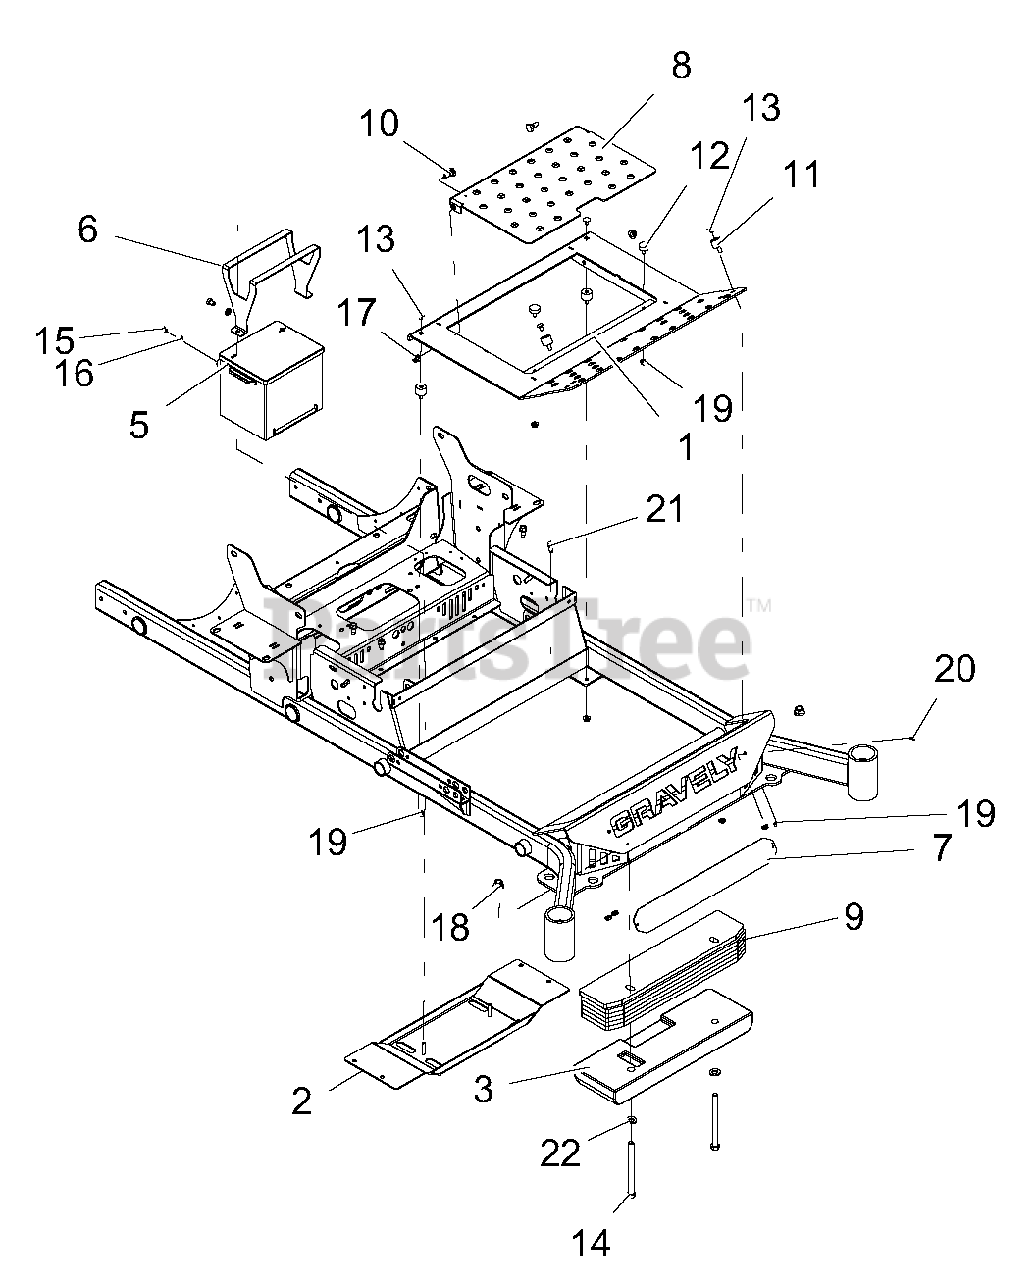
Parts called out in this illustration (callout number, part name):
1	WLDMT, FOOT PLATE-RED
2	WLDMT, PT400 DIESEL BATTERY TRAY
3	WEIGHT, CAST IRON
5	BATTERY, GROUP 70, 540 CCA
6	BRKT, BATTERY HOLD-DOWN
7	PLATE, BUMPER LOGO BACKING-BLACK
8	PANEL, INSPECTION
9	WEIGHT, COUNTER
10	BLT, SHLDR EP .38-16X.30 HEX YZ
11	BUMPER, STUD MOUNTED W/FEMALE INSERT
12	BUMPER, RUBBER
13	@BLT-RDHDSQNK .31-18X.50 G5 YWZC
14	BLT-HEX .50-13X6.00 GR5 YWZC
15	BLT-HEX .38-16X.50 GR5 YWZC
16	@WSHR-LK .38X.094 REG YWZC
17	NUT-LK-NYL-FLG .38-16 YWZC
18	NUT-LK-NYL-FLG .50-13 YWZC
19	@NUT-SPNLK-FLG .312-18 YWZC
20	SCR-TAP .25-20X.50 HWH TR YWZ
21	SCR-TAP .38-16X.75 HWH TR YWZ
22	@WSHR-FL-STL.531X1.06X.095YWZC
